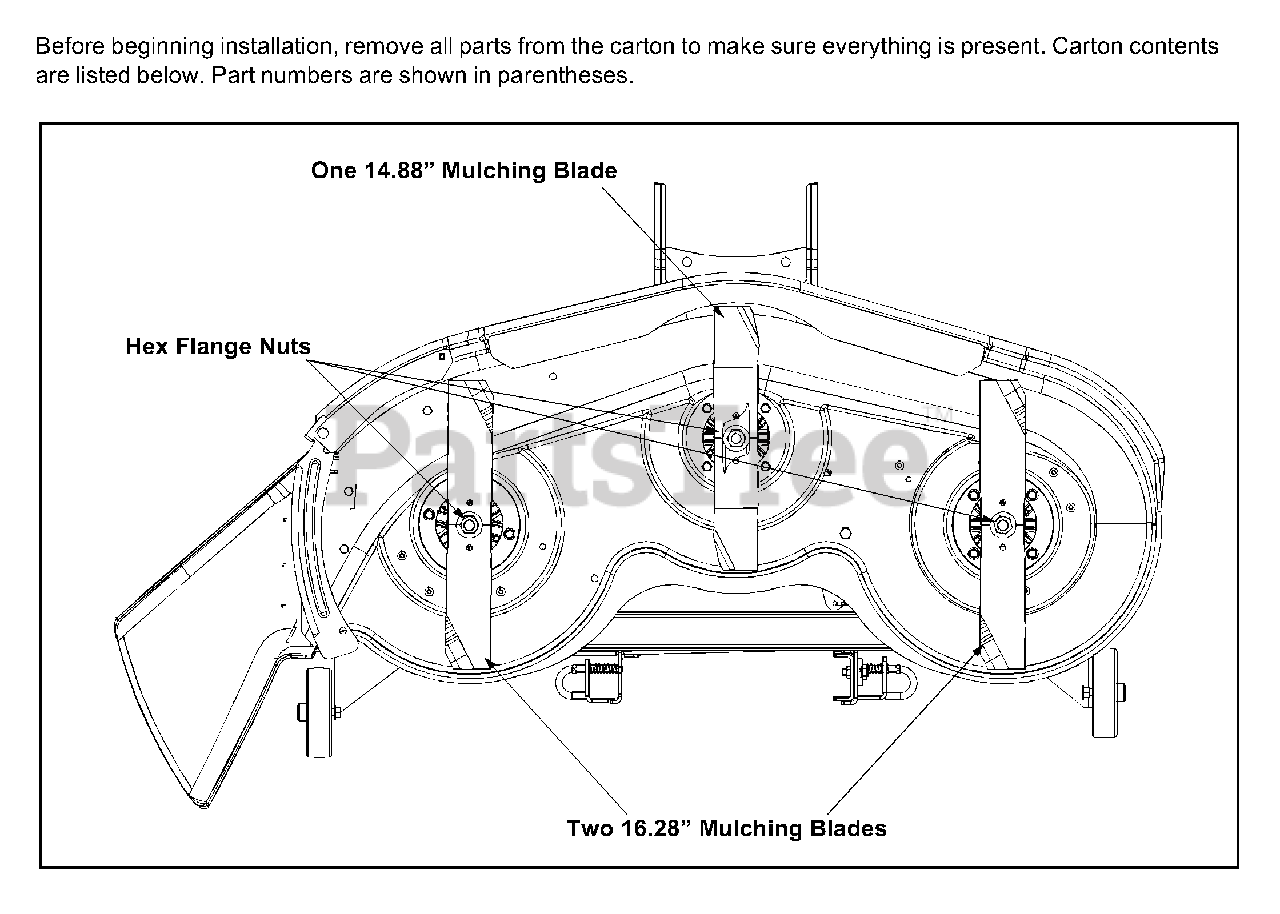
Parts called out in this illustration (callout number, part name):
1	Mulch Plug
2	16.28" Mulching Blades
3	14.88" Mulching Blade
4	Machine Screw, 1/4"
5	Plastic Wing Nut, 1/4"
6	Hex Nut, 1/4"
7	Flat Washer
